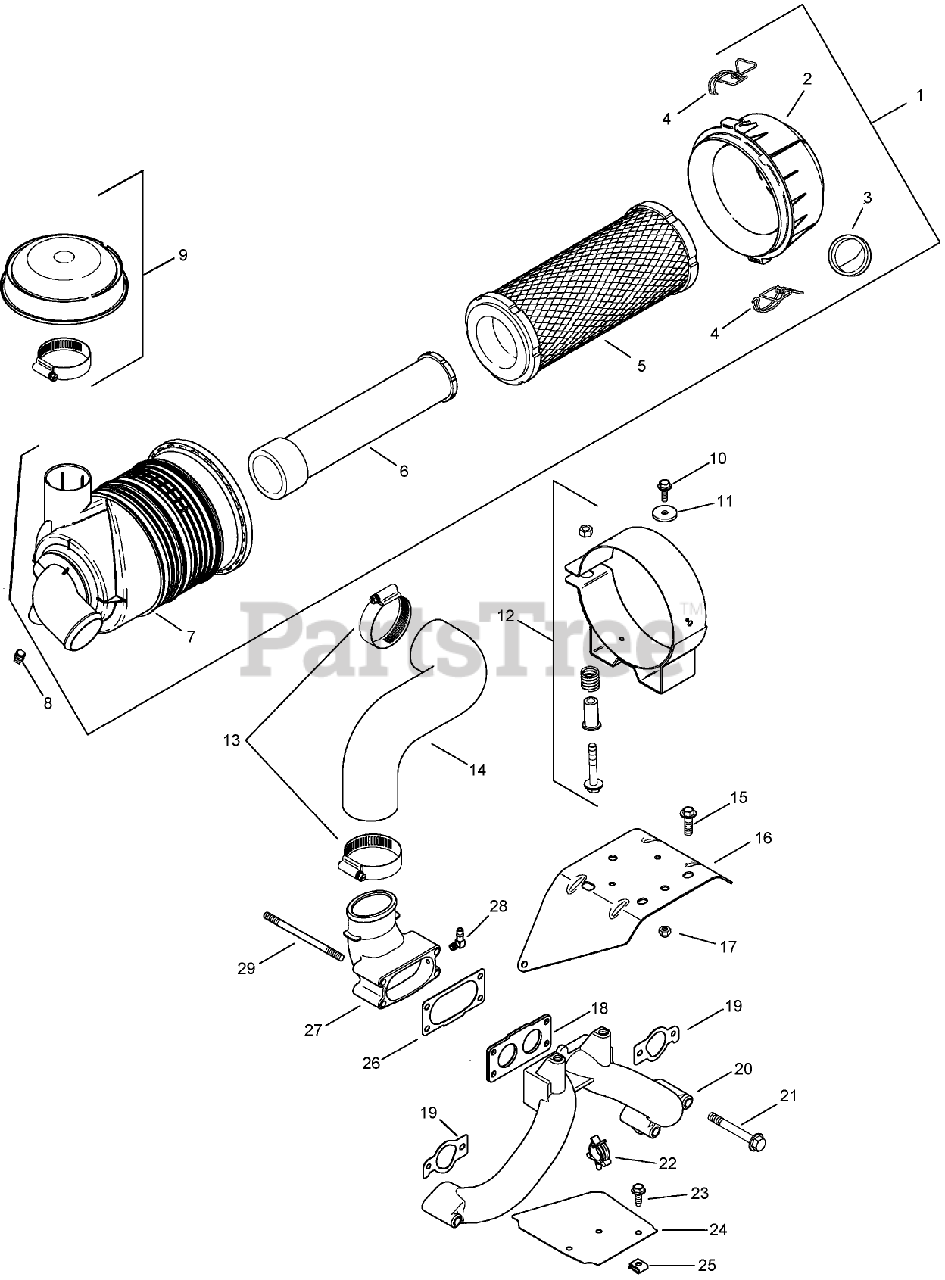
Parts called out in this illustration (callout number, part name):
1	Air Cleaner ASM (Includes 2-7)
2	AIR CLEANER COVER ASM
3	Valve-Ejector, Dust
4	Clip
5	Element-Air Filter, Primary
6	Element-Air Filter, Safety
7	Housing-Air Cleaner, Heavy Duty
8	Plug-Pipe
9	Hood-Cleaner, Air
10	Screw-HF (M6x1.0x16)
11	Washer-Flat (1/4)
12	Air Cleaner Bracket ASM
13	Clamp-Hose
14	Hose-Cleaner, Air
15	SCREW-HF (M8X1.25X20)
16	Bracket-Mounting, Air Cleaner
17	Nut-Lock (M6X1.0)
18	Gasket-Manifold and Carburetor
19	Gasket-Manifold, Intake
20	Manifold-Intake (Includes 17, 18, 25)
21	Screw-HF (M6x1.0x55)
22	Retainer-Clip
23	SCREW-FLANGE, THREAD FORMING (M6X1.0X16)
24	Shield-Debris
25	Clip-Mounting
26	Gasket-Carburetor/Elbow
27	Elbow-Air Cleaner (Includes 25)
28	Connector-Hose
29	STUD-CARBURETOR (M6X1.0X122)
